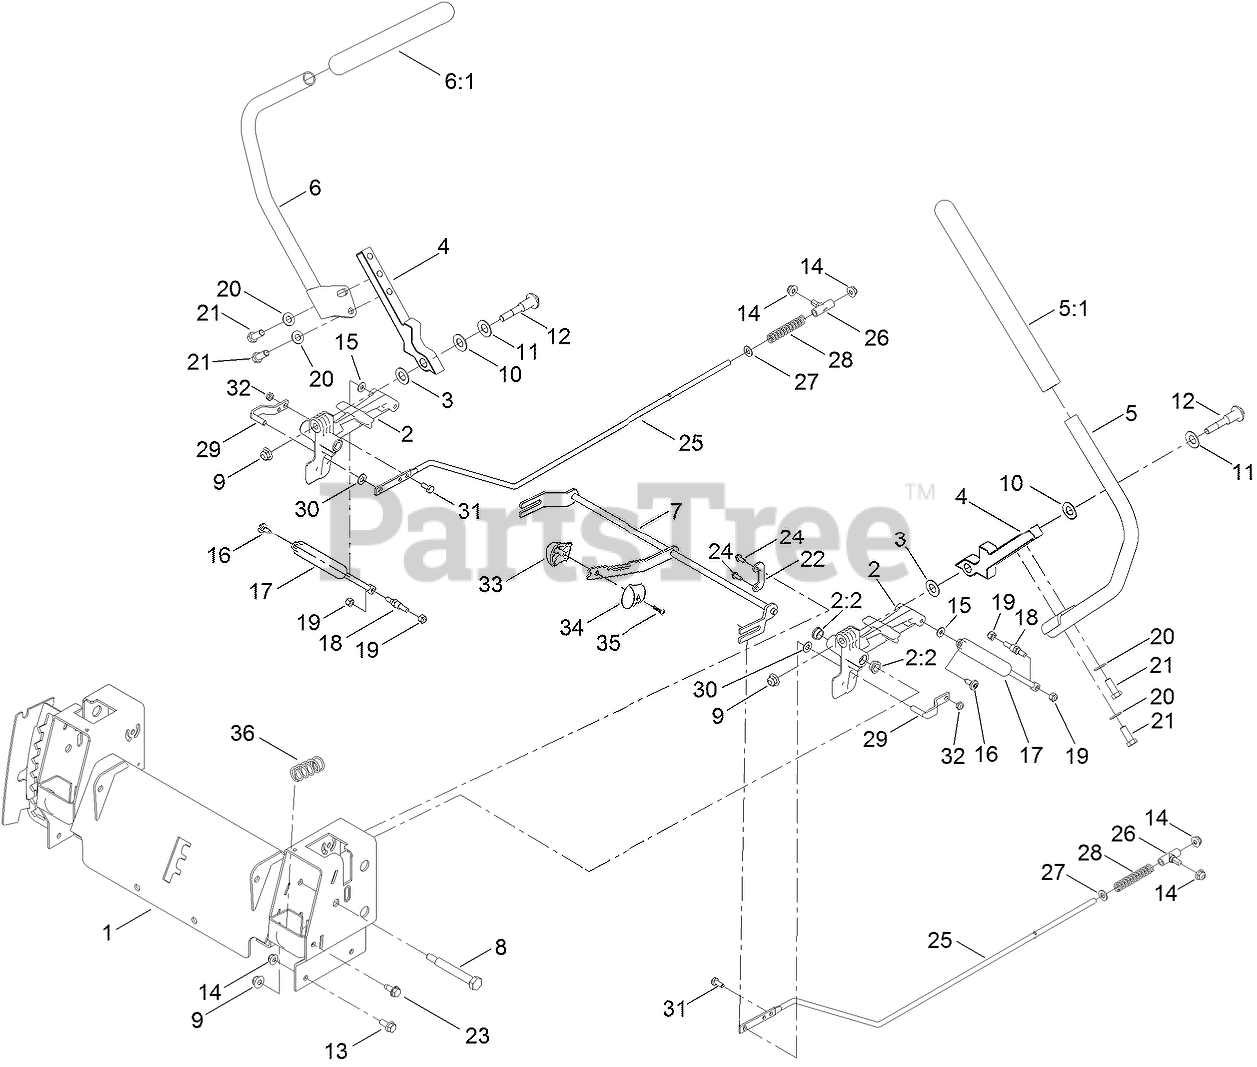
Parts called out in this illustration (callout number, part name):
1	CONTROL BOX ASM
2	ACTUATOR ARM ASM
2:2	BUSHING-FLANGE
3	WASHER-NYLON
4	ARM-CONTROL
5	HANDLE-CONTROL, LH
6	HANDLE-CONTROL, RH
7	SPEED CONTROL ASM
8	BOLT-PIVOT
9	NUT-HF, NI
10	WASHER
11	WASHER-BELLEVILLE
12	BOLT-PIVOT
13	SCREW-HHF
14	NUT-HF
15	WASHER
16	SCREW-SHOULDER
17	DAMPER
18	STUD-DAMPER
19	NUT-HEX
20	WASHER-FLAT
21	SCREW-HH
22	RETAINER
23	SCREW-HWHTF
24	SCREW-TAPTITE
25	ROD-HYDRO
26	MOUNT-ROD, HYDRO
27	WASHER-PLAIN
28	SPRING-COMPRESSION
29	PIN-ROD, HYDRO
30	SPACER-NYLON
31	SCREW-HH
32	NUT-HEX
33	KNOB-RH
34	KNOB-LH
35	SCREW-PPH
36	SPRING-RETURN
